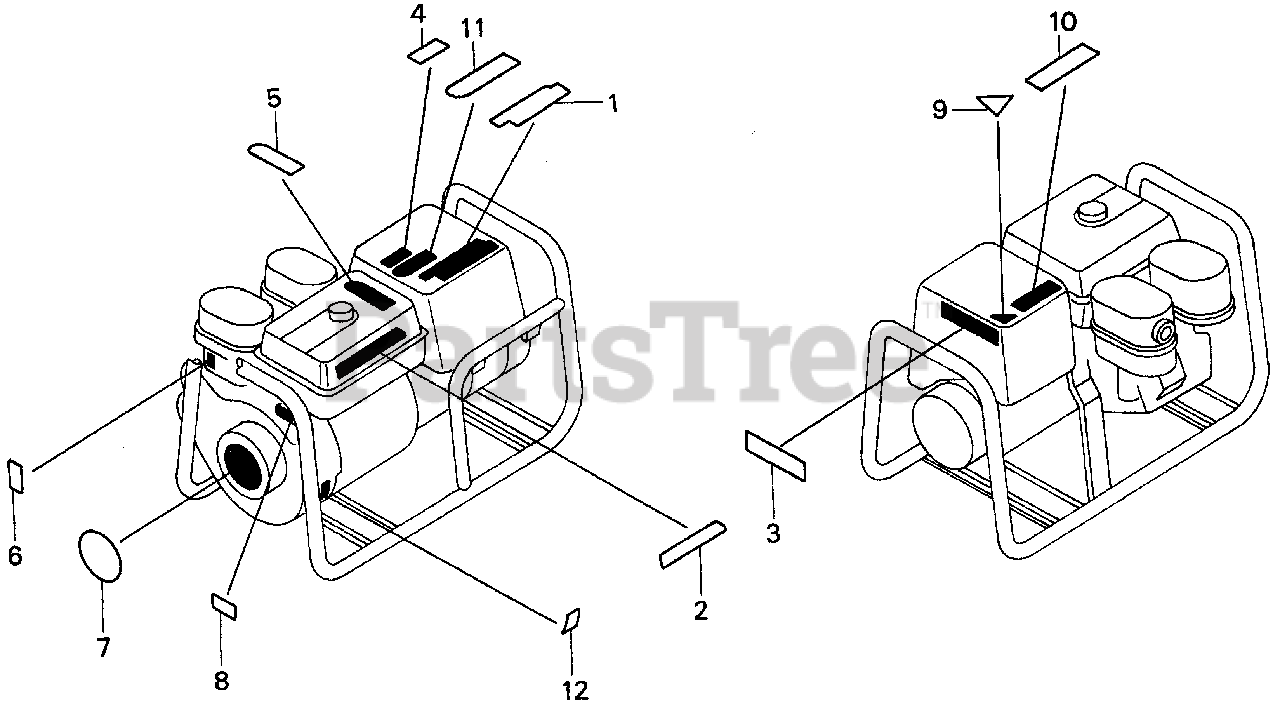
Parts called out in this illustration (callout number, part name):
1	EMBLEM (NOT AVAILABLE)
2	EMBLEM, FUEL TANK
3	PLATE, CAUTION
4	LABEL, RAIN WARNING (ENGLISH)
5	MARK, CAUTION (ENGLISH/FRENCH)(SPANISH)
6	MARK, CHOKE (EXTERNAL)
7	MARK, OIL ALERT (NOT AVAILABLE)
8	MARK, OIL ALERT (EXTERNAL)
10	MARK, CAUTION (CO)(ENGLISH/FRENCH)(SPANISH)
11	LABEL, CONNECT WARNING (ENGLISH)
12	MARK, OIL CAUTION
